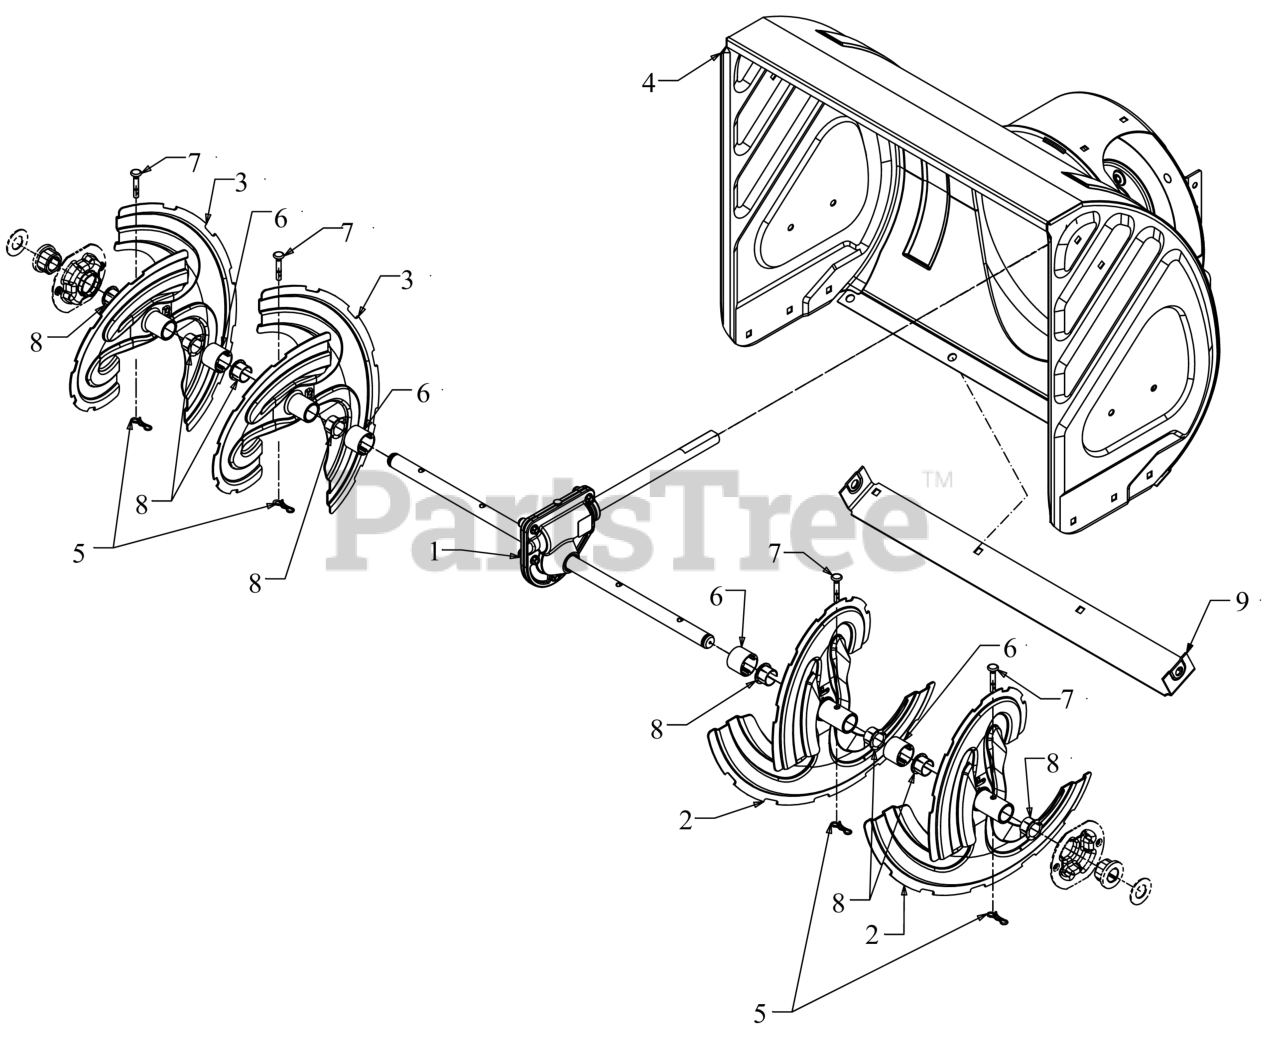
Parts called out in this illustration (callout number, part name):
1	24" GEARBOX ASSEMBLY
2	10T SPIRAL (LH)
3	10T SPIRAL (RH)
5	BOW TIE COTTER PIN 1/4-5/16
6	SPACER 1.25OD x .75ID X1.00 LG
7	SHEAR PIN .25 x 1.50 GR2
7	Cub Cadet SHEAR PINS (2X SNOW)
7	SHEAR PINS QTY 4
8	FLANGE BUSHING
